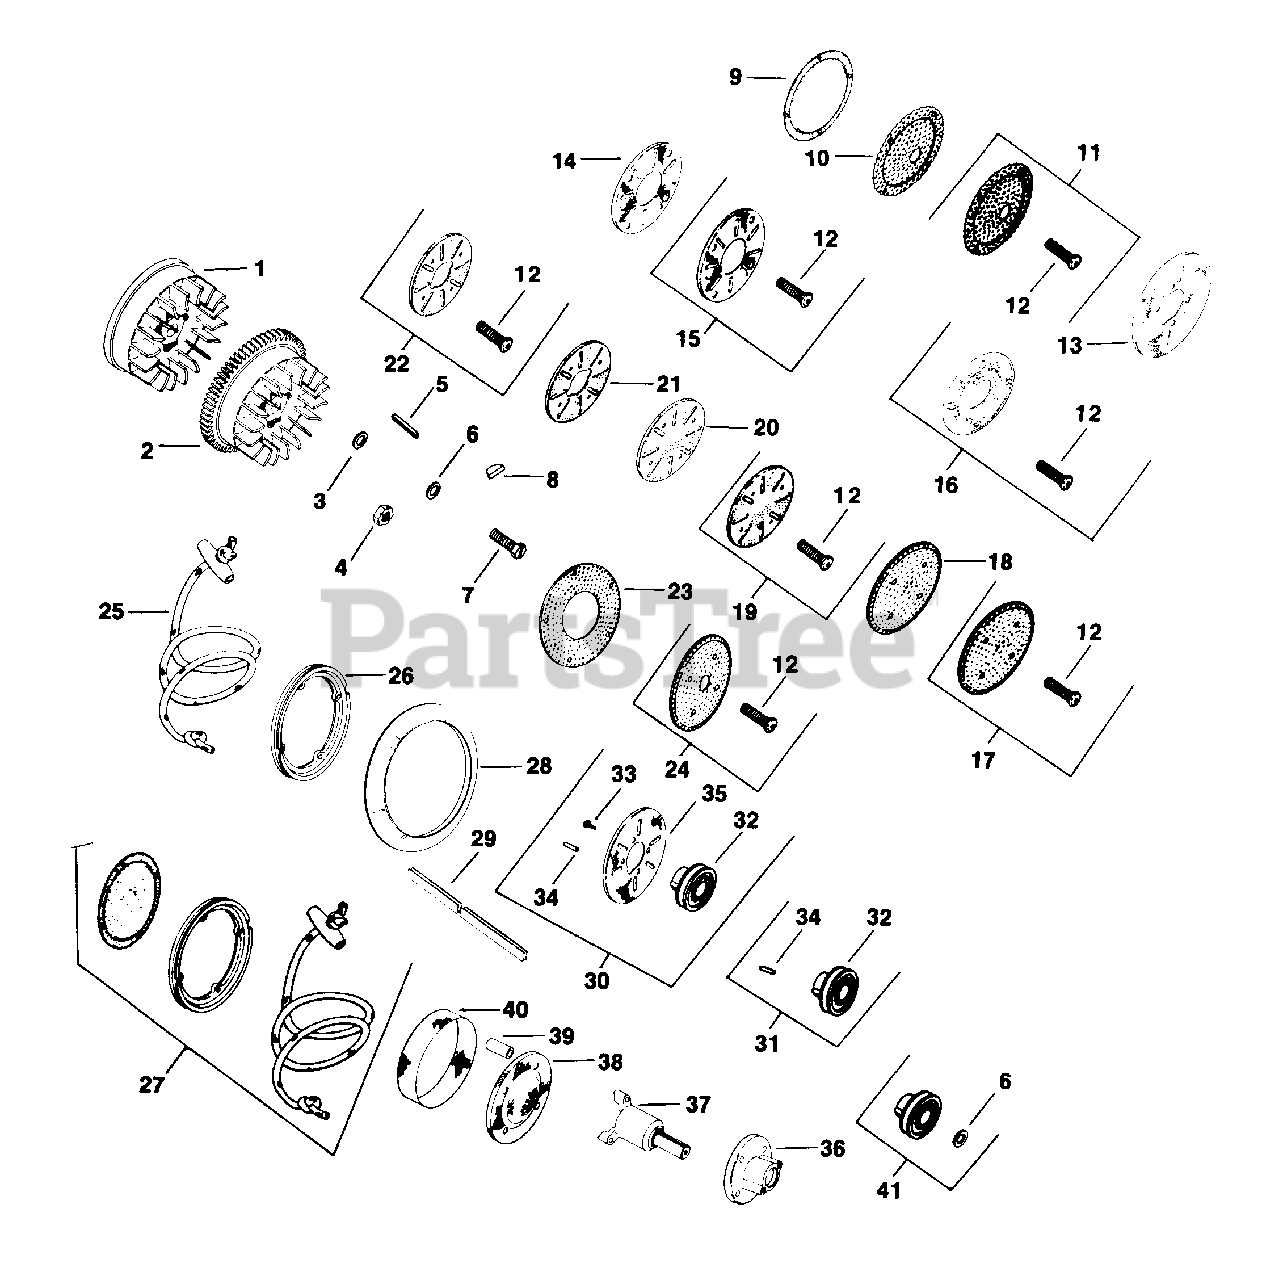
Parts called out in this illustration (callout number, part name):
3	WASHER - DISCONTINUED
4	NUT - USE 25 100 02
5	KEY - DISCONTINUED
6	WASHER - USE 52 468 15
7	SCREW - USE 25 086 24
8	KEY, 3/16" X 1"
9	SCREEN, GRASS
25	ROPE-DISCONTINUED
26	PULLEY
